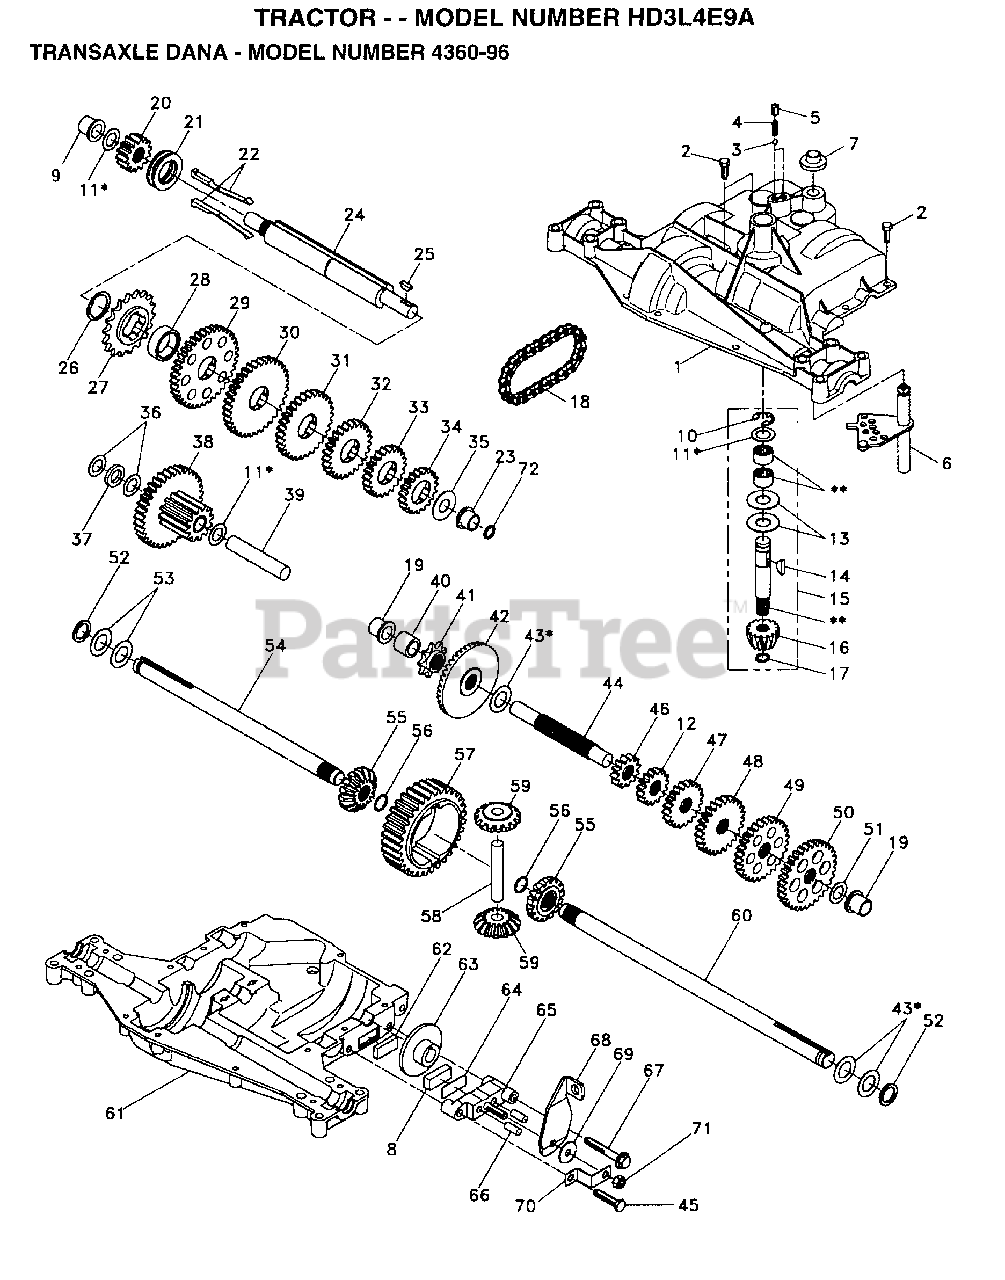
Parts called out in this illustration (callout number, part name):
1	HARNESS.IGNITION
4	"SPRING, DETENT LT"
5	"SCREW, SET LT"
6	KIT SHIFTER ASM
7	SHIFTER BOOT
8	PUCK T
10	RETAINING RING LT
11	ASM KIT SHIM 4689
12	PLUG.PLASTIC
13	WASHER T
14	KEY WOODRUFF-DANA
17	"RING,RETAINING LT"
18	"CHAIN,24 PTCH LT"
19	BEARING.FLNG.5510
20	GEAR SPUR 14 TTH
21	CLUTCH.COL.5467
22	KIT.ASM.CLUTCH KY
23	BEARING.FLNG.5511
24	SHAFT INTERM DANA
25	WOODRUFF KEY
26	"RING,RETAINING LT"
27	SPROCKET 18T T
28	SPACER YT
29	GEAR SPUR 37 TTH
30	GEAR SPUR 35 TTH
31	GEAR SPUR 30T
32	GEAR 25T LT
33	GEAR SPUR 22 TT
34	SPUR GEAR 19T
35	"WASHER, PLAIN LT"
36	WASHER 025
37	SPACER
38	ASSM GEAR COMB
39	SHAFT IDLER
40	SPACER T
41	SPROCKET 9T LT
43	ASM KIT SHIM
44	SHAFT T
45	"SCREW, TAPPING LT"
46	GEAR SPUR 12 TTH
48	"GEAR, SPUR 25T LT"
49	GEAR 28T T
50	"GEAR, SPUR 31T LT"
51	WASHER 060
52	NEOPRENE WASHER
53	WASHER 031
55	GEAR 15T T
56	"RING,RETAINING LT"
58	SHAFT T
59	GEAR 1ST T
61	HOUSING LOWER TNS
62	PUCK T
63	BRAKE DISC. T
64	SPACER LT
66	PIN T
69	WASHER LT
71	NUT.LOCK.5/16-24
72	SEAL.OIL.DAN.5508
